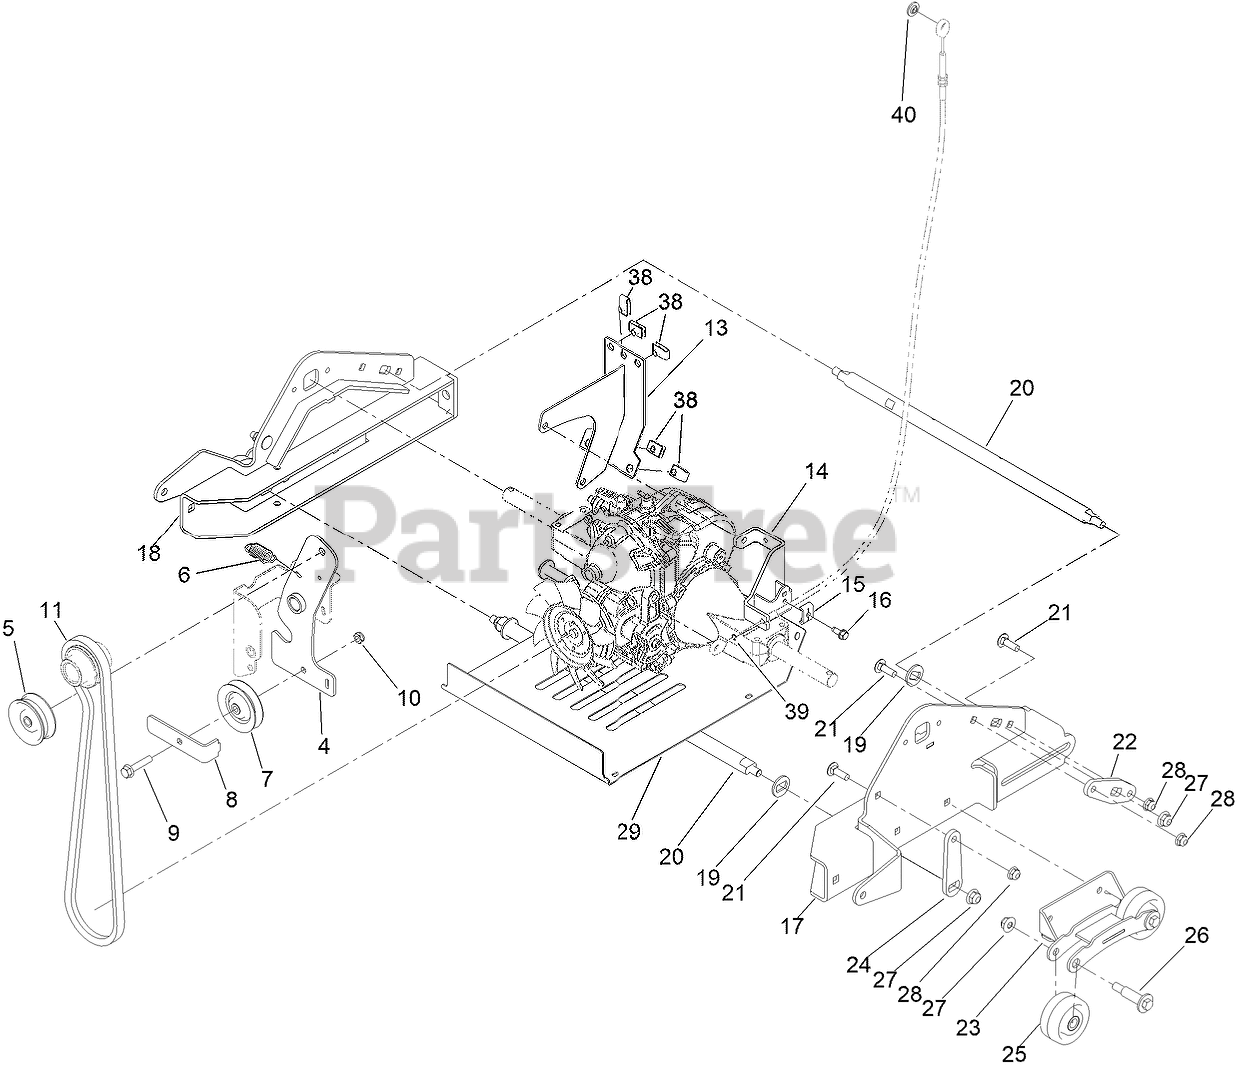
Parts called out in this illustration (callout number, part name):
4	ARM-CLUTCH, TRACTION WELD ASM
5	PULLEY-IDLER
6	SPRING-EXTENSION
7	PULLEY-IDLER
8	GUIDE-BELT
9	SCREW-HHF
10	NUT-HEX
11	BELT-TRACTION (A, 41.00)
13	SUPPORT-HYDRO, REAR WELD ASM
14	BRACKET-HYDRO, WELD ASM
15	CLAMP-CABLE
16	SCREW-HWH
17	SUPPORT-TRACK, ASM LH
18	SUPPORT-TRACK, ASM RH
19	WASHER-SPECIAL, D
20	BAR-PIVOT
21	BOLT-CARR
22	PLATE-BAR, PIVOT
23	SUPPORT-WHEEL, ASM
24	PLATE-SUPPORT
25	WHEEL-BOGEY
26	BOLT-SHOULDER
27	NUT-HF, NI
28	NUT-HF
29	COVER-BOTTOM
39	RING-RETAINING, EXT
40	WASHER-STEPPED
